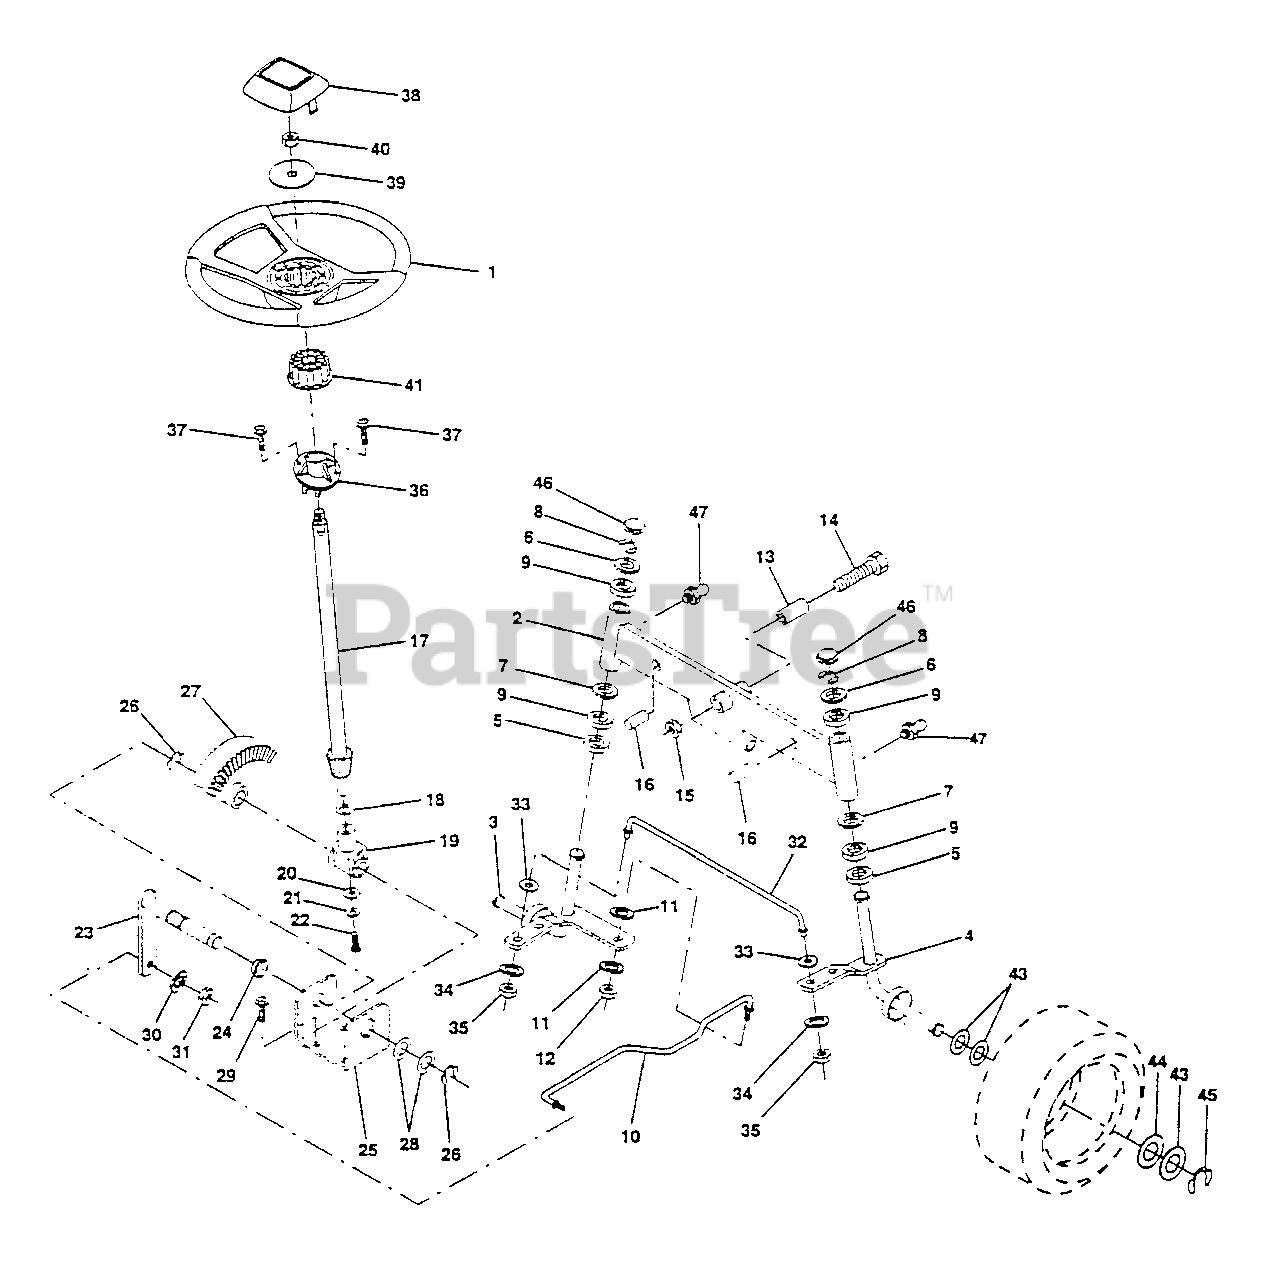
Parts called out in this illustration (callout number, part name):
1	Wheel Steering Auto Grey
2	Axle Asm Fr LT W/gzks 38/42
3	Spindle Asm LH
4	Spindle Asm RH
5	Bearing Race Thrust Harden
6	Washer 25/32 X 1-5/8 X 16 Ga
7	Washer 27/32 X 1-1/4 X 16 Ga
8	Ring Klip #t5304-75
9	Bearing Col Strg Blk
10	Link Drag Sol Ball Jt 20 064
11	Washer Lock Hvy Hlcl Spr 3/8
12	Nut Fin Hex 3/8-24 Unf
13	Spacer Bearing Axle Front
14	Bolt Hex 5/8-11 Unc X 3-1/2
15	Nut Lock Flange 5/8-11 Unc
16	Pin Axle 5/8 X 1 55/1 54 Lg
17	Shaft Asm Strg 20 31 x 3/4 YP YT
18	Washer Thrust 515x 750x 033
19	Support Shaft
20	Washer Shim 1/4 X 5/8 X 062
21	Washer Lock Hvy Helical 1/4
22	Screw Hex Socket 1/4-20 X 5/8
23	Shaft Asm Pittman
24	Nyliner Snap In
25	Bracket Steering
26	Ring Klip #t5304-75
27	Gear Sector
28	Bearing Race Thrust Harden
29	Screw Thdrol 3/8-16x3/4 Ty-tt
30	Washer Lock Hvy Hlcl Spr 3/8
31	Nut Fin Hex 3/8-24 Unf
32	Rod Tie Wire Form 19 75 Elec
33	Washer 11/32 x 3/4 x 16 Ga.
34	Washer, Lock Hvy Hlcl Spr 5/16
35	Locknut 5/16-24 Unf
36	Bushing Strg Blk 7421747 Id
37	Screw Slftp #10-16 X 1/2 Ty-b
38	Insert Cap Strg Wh Aut Hus Gry
39	Washer 53 X 2 25 X 160 Zinc
40	Nut Hex Jam Toplock 1/2-20 Unf
41	Adapter Wheel Strg 758/ 753id
43	Washer 25/32 X 1 1/4 X 16 Ga
44	Washer 25/32 X 1-5/8 X 16 Ga
45	Ring Klip #t5304-75
46	Cap Spindle Fr Top Blk
47	Fitting Grease
